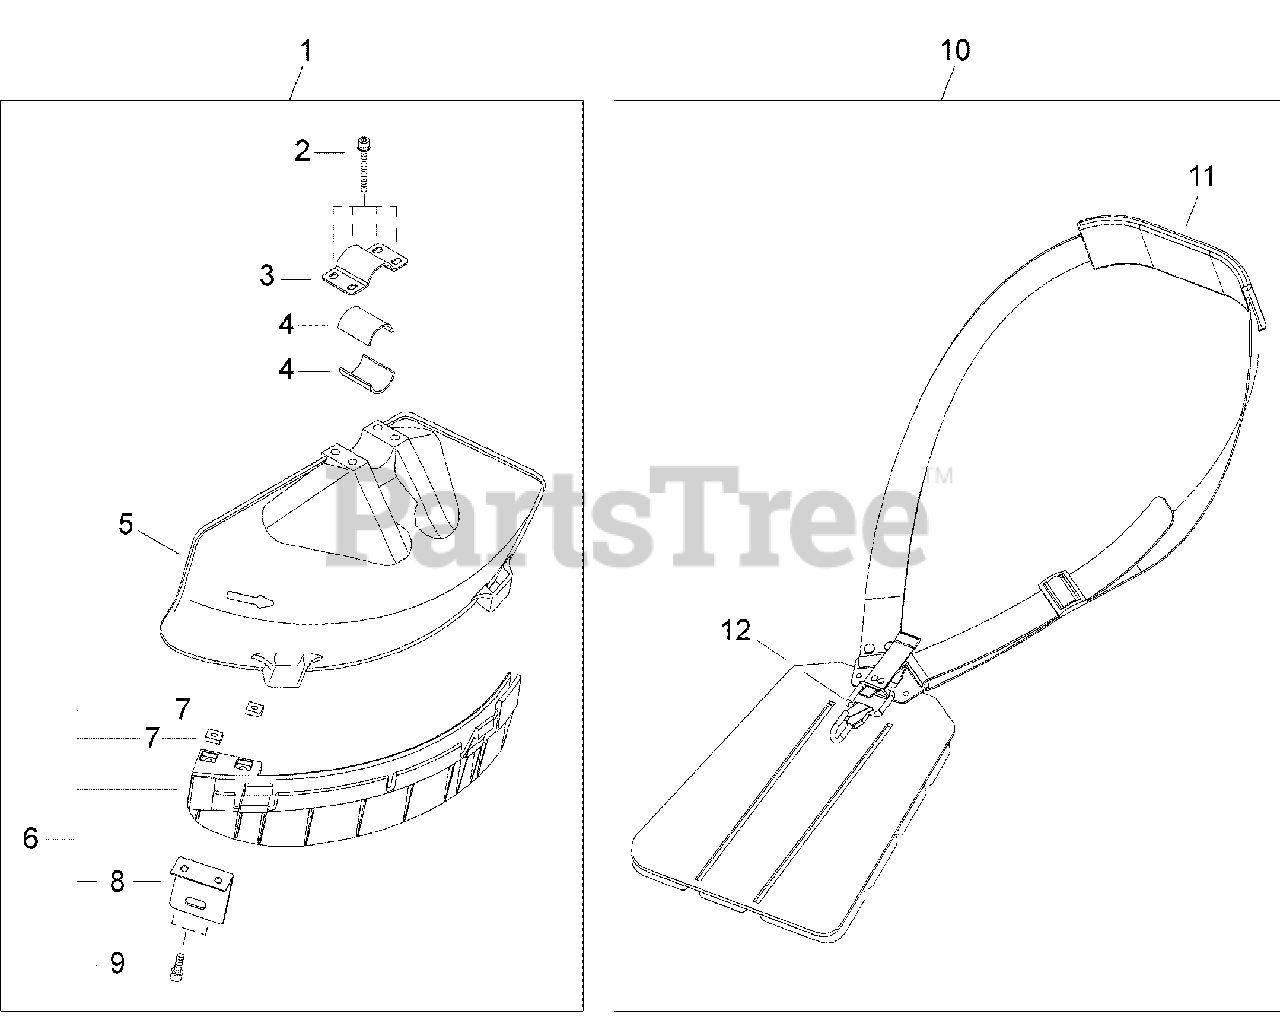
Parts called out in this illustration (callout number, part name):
1	DEBRIS SHIELD KIT
2	SCREW - 5X45
3	CLAMP - UPPER
4	SPACER
5	SHIELD, DEBRIS
6	SHIELD GUARD KIT
7	NUT - 5
8	KNIFE, TRIMMER LINE
9	SCREW - 5X16
10	HARNESS ASSY
11	PAD
12	HOOK
